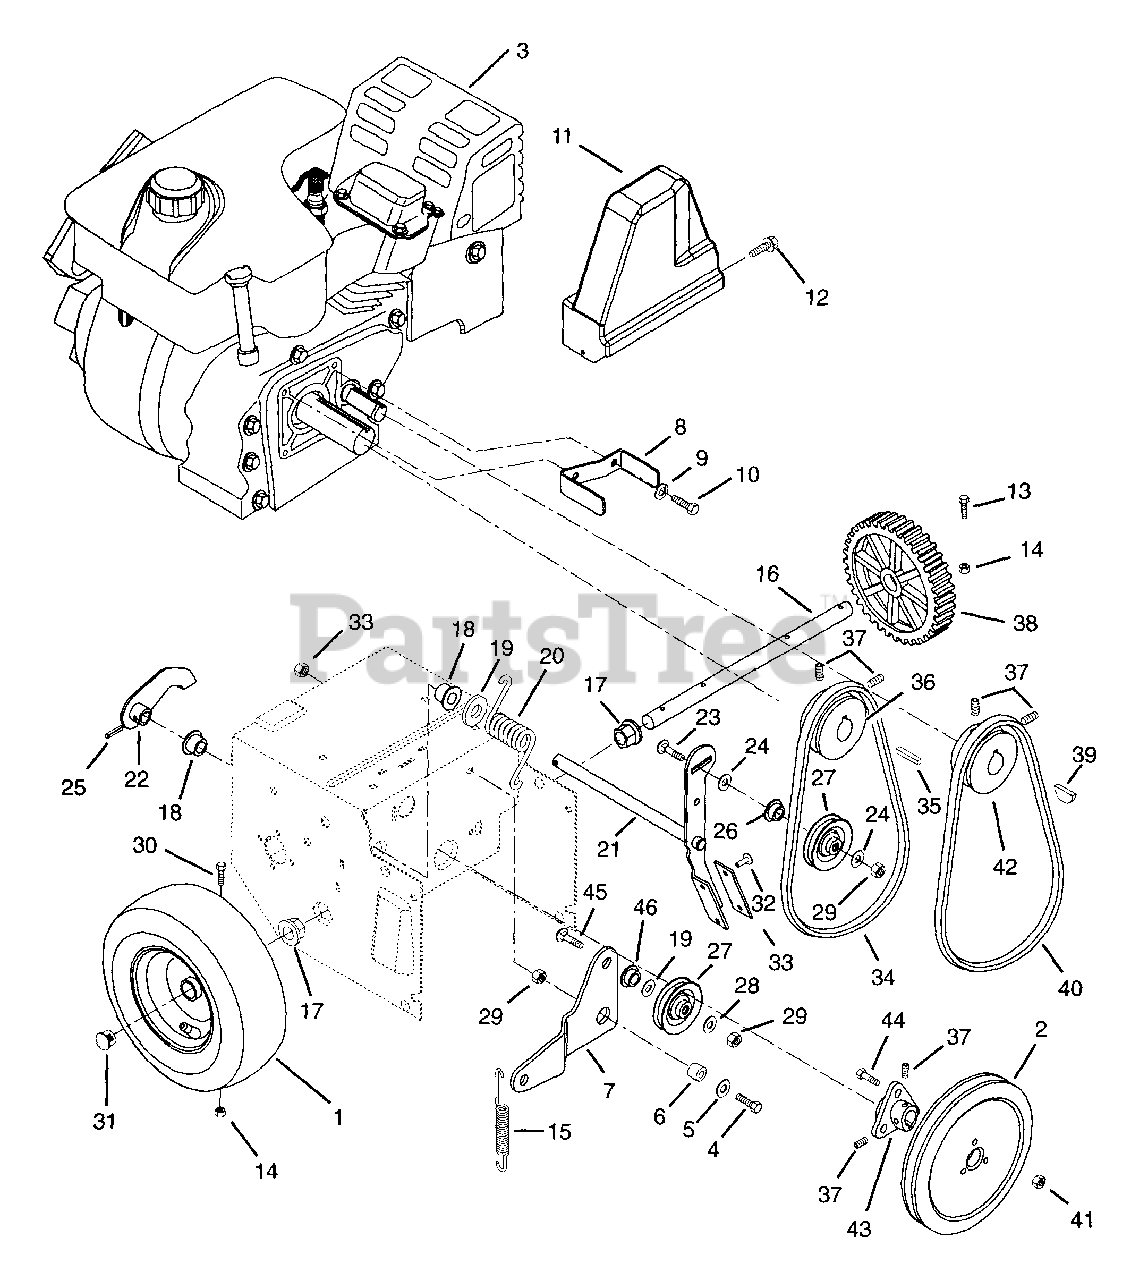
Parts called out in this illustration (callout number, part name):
1	WHEEL -
1	TIRE
1	TIRE/WHEEL ASSY
2	PLY-V 8.0 X 1.25 3BLT SALEM
3	7HP TECUMSEH OHV REGENCY
4	@BLT-HEX .31-18X.75 GR5 YWZC
5	@WSHR-FL-STL.38X.875X.083 YWZC
6	SPACER BUSHING .5 X .32 X .163
7	IDLER ARM
8	FINGER, BELT
9	@WSHR-LK .31X.078 REG YWZC
10	BLT-HEX .31-24X.75 YWZC GR5
11	COVER, BELT
12	@SCR-TAP .25-20X.37 HWH YWZ TR
13	BLT-HEX .25-20X1.75 GR8 YWZC
14	@NUT-LK-CTR .25-20 YWZC
15	SG-TENS .047X.44X3.37 WLD 1.47
16	AXLE SHAFT
17	BSHG-FLG .750X.873HEXX.53X1.18
18	BSHG-FLG.500X.625X.312X.750NY
19	WSHR-FL-STL .520X.810X.033YWZC
20	SG-TORS .148X1.0X1.53
21	CLUTCH ARM W/BRAKE PAD
22	ARM-CLUTCH
23	@BLT-RDHDSQNK .31-18X1.25 G5YZ
24	@WSHR-FL-STL.38X.875X.083 YWZC
25	PIN-ROLL .156X.88
26	SPCR, BRG .315X.50X.688X.281
27	IDLER
28	@WSHR-FL-STL.38X.875X.083 YWZC
29	@NUT-LK-CTR .31-18 YWZC
30	BLT-HEX .25-20X1.75 GR8 YWZC
31	HOLE PLUG
32	RVT-TBLR .187X.437 RH ST PL
33	BRAKE LINING
34	V-BELT, 4L-RAW EDGE
35	KEY-SQ .188X1.0X.188 SAE 8630
36	SHEAVE - ENGINE
37	SCR-SET .31-18X.38 SKHCUPDL
39	KEY-WDRF .125X.625X.250 SAE5
40	V-BELT, 3L-COGGED
41	@NUT-SPNLK-FLG .312-18 YWZC
42	SHEAVE - CAMSHAFT
44	BLT-SERRDHD SL .31-18X.75 YZ
45	@BLT-RDHDSQNK .31-18X1.25 G5YZ
46	BSHG, FLG .325X.499X.26X.88
